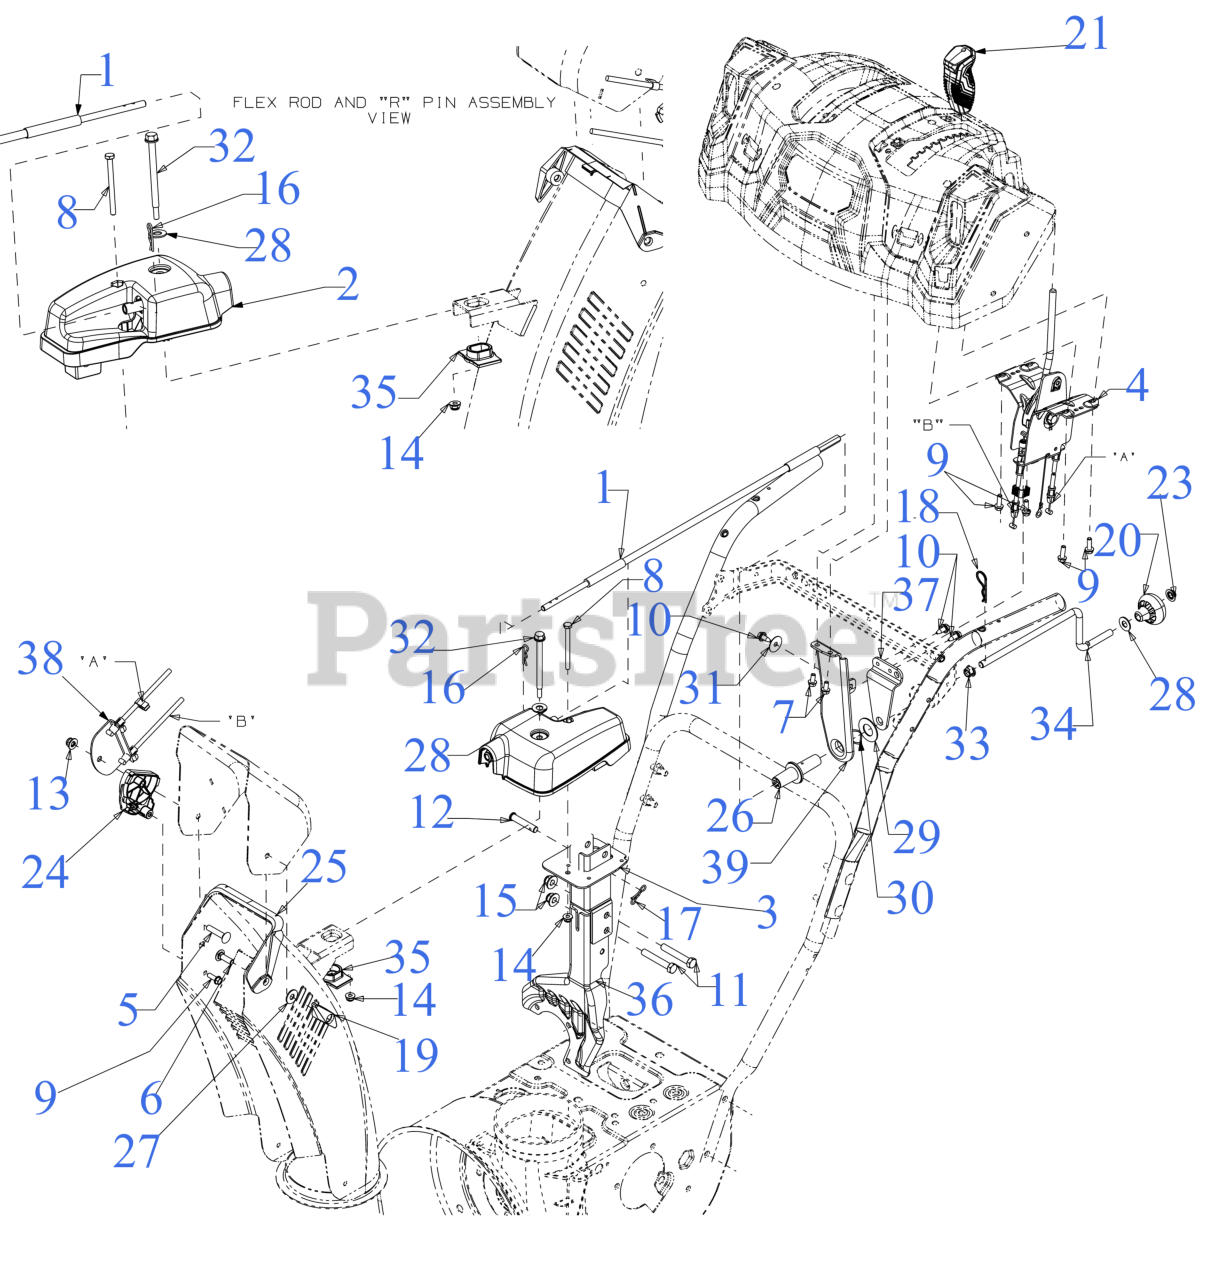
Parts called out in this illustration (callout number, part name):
1	CHUTE CONTROL
2	2-WAY CHUTE ROTATE GEARBOX
3	EXTENSION CHUTE MAST
4	Not Serviceable/ Components Only
5	CARRIAGE BOLT 5/16-18 x 1.50
6	CARRIAGE BOLT 5/16-18 x 1.00
7	HEX SCREW 1/4-15 x .50
8	SCREW 1/4-20 x 3.0 GR5
9	SCREW 1/4-15 x .750
10	SCREW 1/4-20X.625
11	SCREW 3/8-16 x 2.25 GR5
12	CLEVIS PIN 3/8 x 1.87
13	FLANGE LOCK NUT 5/16-18
14	FLANGE LOCK NUT
16	INTERNAL COTTER PIN
17	BOW TIE COTTER PIN 1/4-5/16
18	INTERNAL COTTER PIN
19	WING KNOB NUT
20	SHIFT KNOB
23	PUSH NUT
24	CHUTE TILT GUIDE
25	UPPER CHUTE ADAPTER
26	CHUTE ROD COUPLER
27	FLAT WASHER
28	FLAT WASHER
29	FLAT WASHER
30	WAVE WASHER .785X1.00X.012
31	FLAT WASHER
32	SHOULDER SCREW
33	BUSHING .380 ID
34	CHUTE CRANK (POWDER BLACK)
35	HELICAL GEAR CHUTE ADAPTER
37	ROD SUPPORT BRACKET
